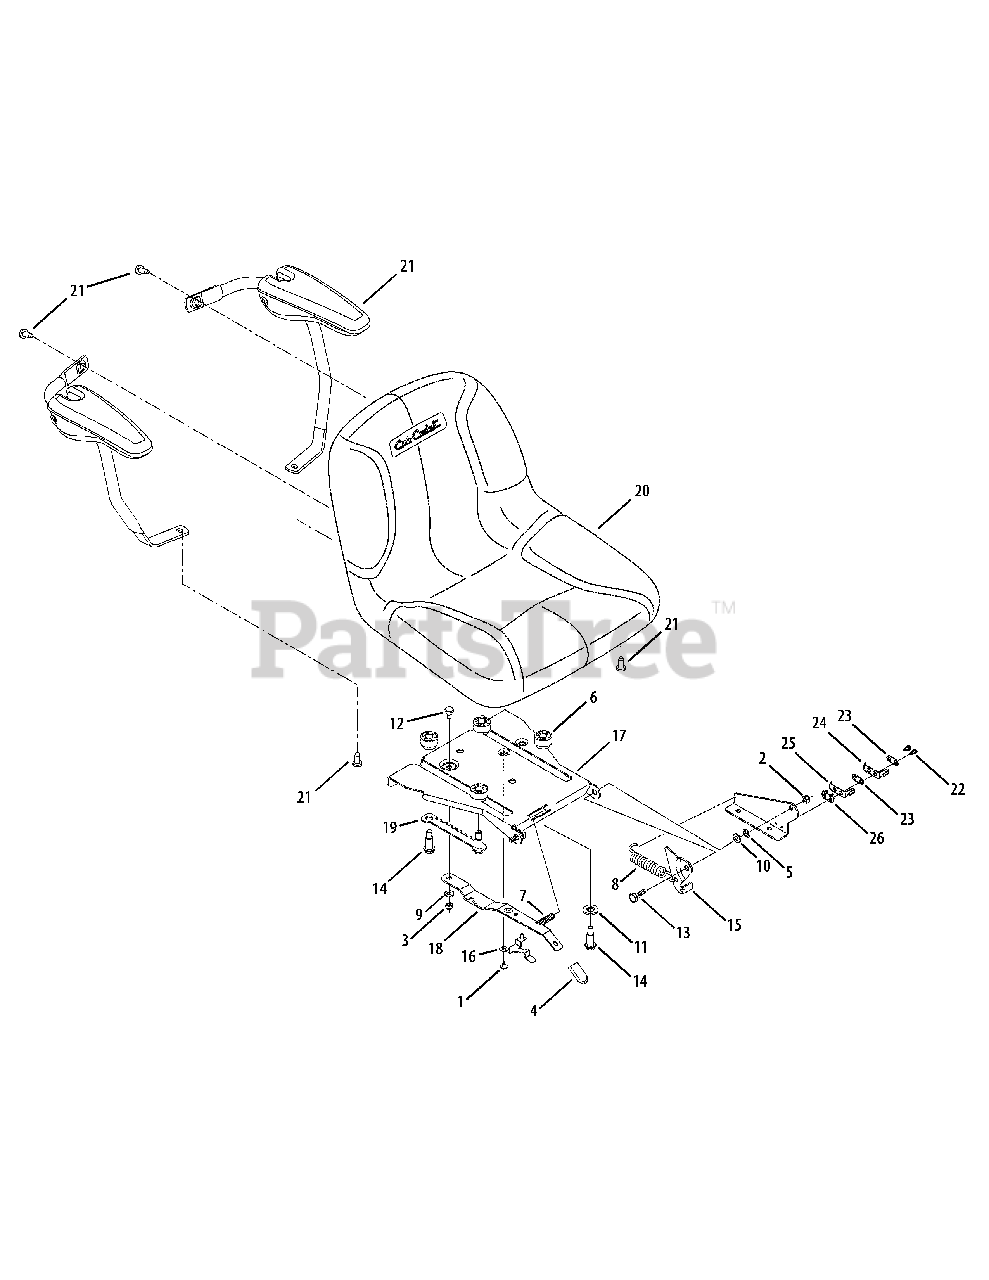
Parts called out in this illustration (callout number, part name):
1	Screw, #10-16, 0.375
2	Nut, Nylon Lock, 5/16-18, Gr5
3	Nut, Nylon Lock, 1/4-20 GrF
4	Grip, Seat, Adjustment
5	Nut, Speed, .3125 ID
6	Spacer, Seat, Adjustment
7	Spring, Compression .41 x 1.50
8	Spring, Extension, .80 Dia x 4.6
9	Washer, Flat, .344 x ..620 x .033
10	Washer, Flat, .340 x .872 x .060
11	Washer, Flat, .531 x 1.062 x .134
12	Screw, Shlder, .340 x .285, 1/4-20
13	Shoulder, Screw .437 x .286 Lg
14	Screw, Shoulder, .50 x.925, 3/8-16
15	LH Bracket, Seat Lift
16	Stop, Seat, Adjustment
19	Selector, Seat, Adjustment
20	Seat, Cub Cadet, High Back
21	Arm Rest Kit
22	Screw, #8-18 x .50
23	Plate, Insulator
24	Spring Switch, Outer
25	Spring Switch, Inner
26	Plate, Insulator Boss
